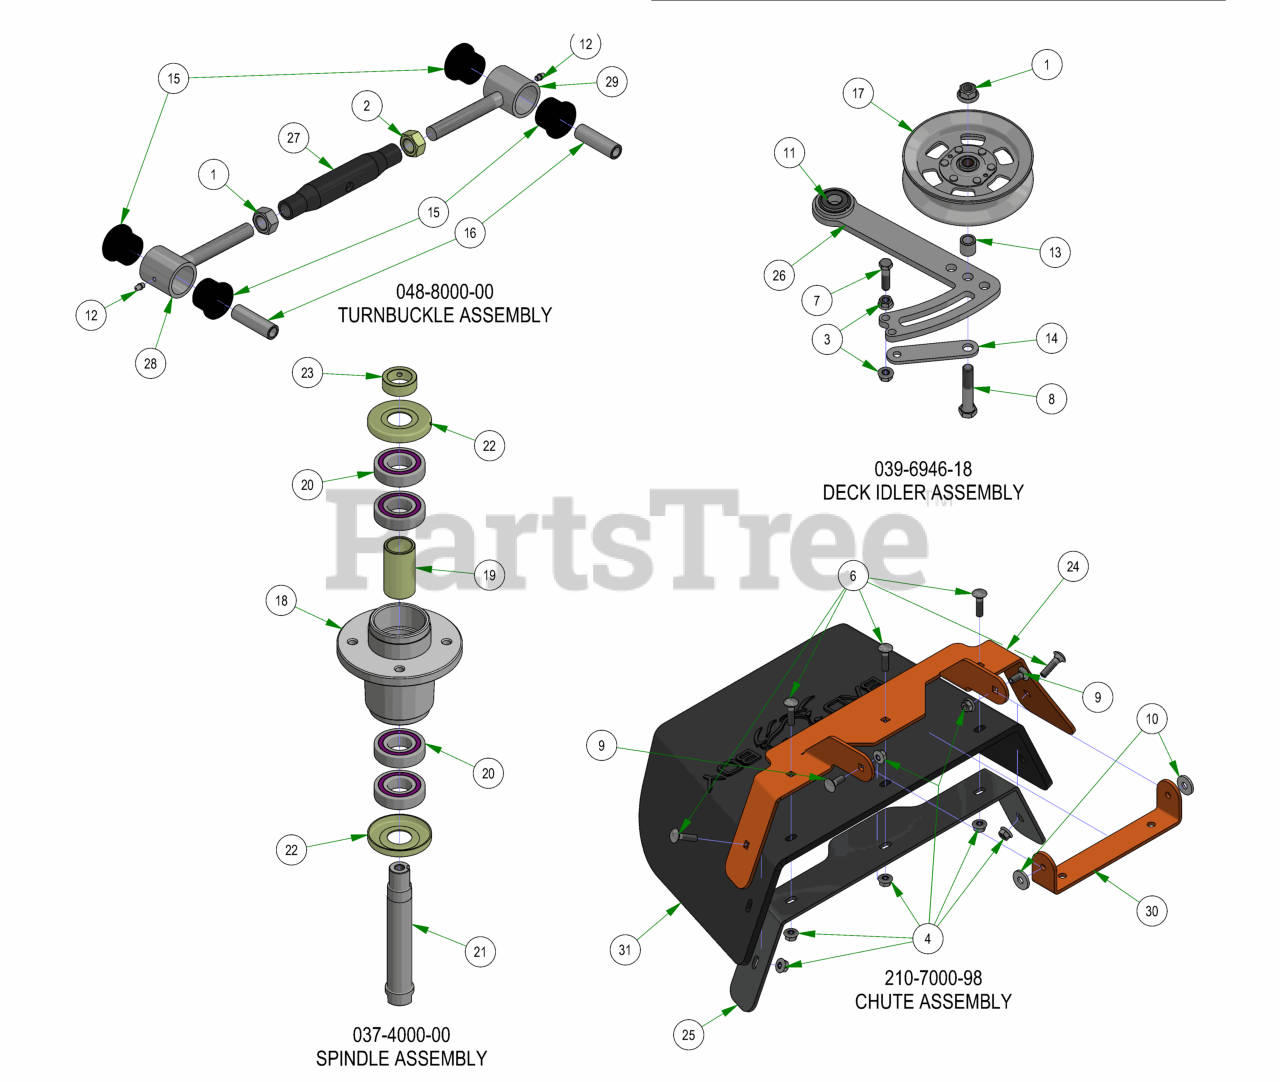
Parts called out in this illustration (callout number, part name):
1	Hex Nut M20-2.5
1	1 2-13 NYLON INSERT FLANGE LOCKNUT ZINC
2	Hex Nut M20-2.5 Left Hand Threads Gold Plated
3	3 8-16 HEX SERRATED FLANGE NUT HARD ZINC
4	5 16-18 NYLON INSERT FLANGE LOCKNUT ZINC
6	5 16-18 X 1-1 4 CARRIAGE BOLT ZINC
7	3 8-16 X 1-1 2 HEX CAP SCREW (GR.5) ZINC
8	1 2-13 X 2-3 4 HEX CAP SCREW (GR.5) ZINC
9	5 16-18 X 7 8 CARRIAGE BOLT ZINC
10	.360 ID X .983 OD X .120 THICK FLAT WASHER NYLON
11	Ball Bearing w Retainer, 99502H-NR, .625 Bore x 1.375 OD x .4375 Width
12	1 4-28 Grease Fitting
13	.51 ID X .75 OD X .75 LGTH SOLID SPACER ZINC
14	Belt Tensioner Retainer Plate
15	Polyeurethane Bushing
17	5" Idler Pully
18	4000 Series Spindle Housing
19	4000 Series Spindle Spacer
20	Bearing - 6206
21	Spindle Shaft
22	Spindle Dust Cap
23	Locking Collar w 1 4"-20 Set Screw
24	2019 Upper Chute Bracket
25	2019 Lower Chute Bracket
26	2019 Deck Belt Tensioner
27	2024 Turnbuckle Body
28	Turnbuckle End Right-Handed Thread
29	Turnbuckle End Left-Handed Thread
30	2019 Chute Hanger
31	2019 Belted Chute with Logo
